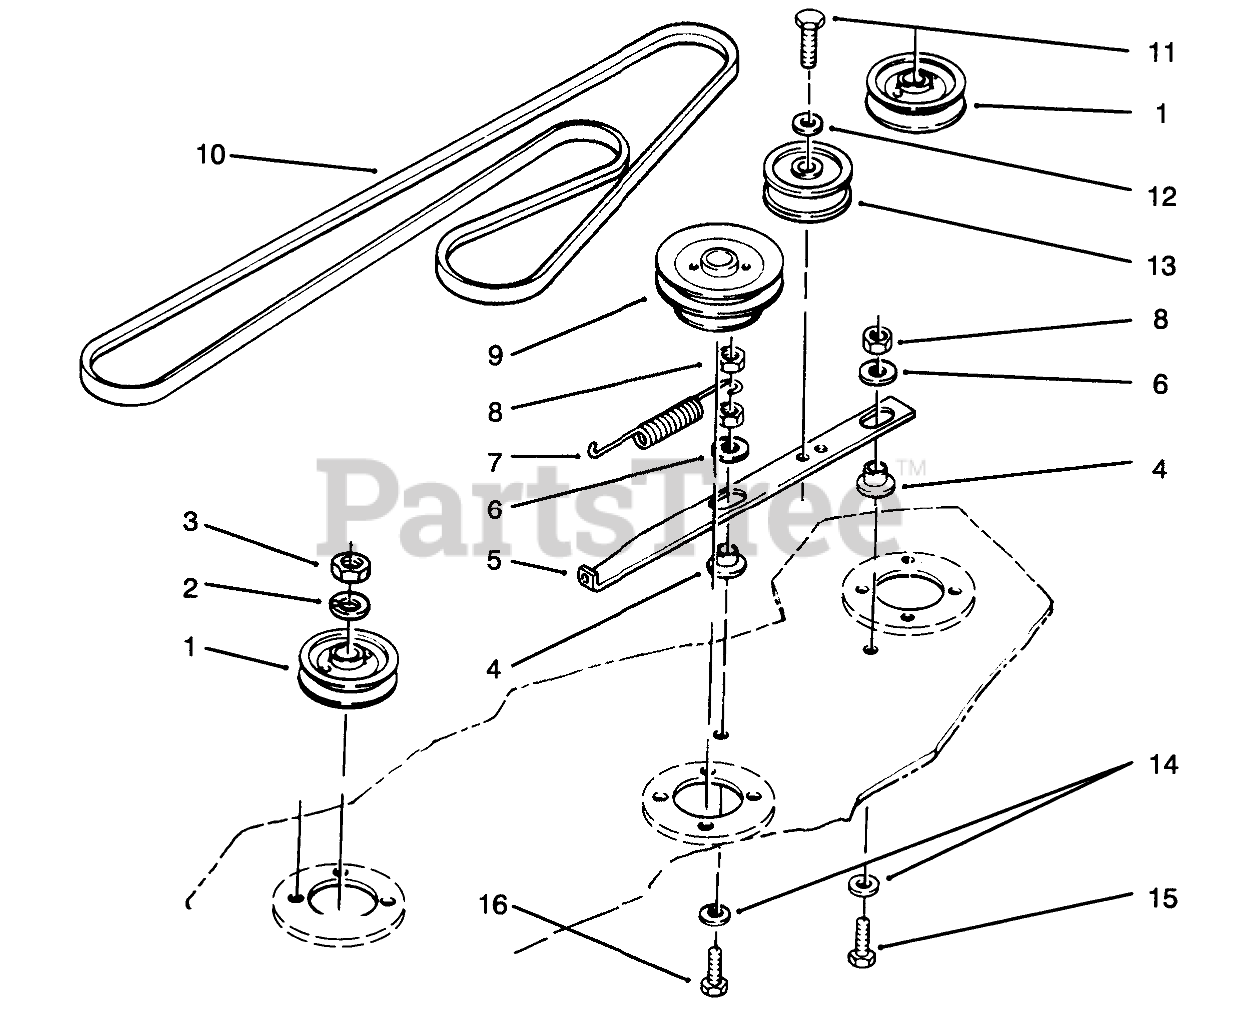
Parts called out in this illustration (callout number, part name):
1	PULLEY
2	WASHER-LOCK
3	NUT-JAM
4	SPACER-BUSHING
5	BAR-IDLER SUPPORT
6	WASHER
7	SPRING-EXTENSION
8	NUT-LOCK, NI
9	PULLEY
10	V-BELT
11	SCREW-HH
12	Washer-Lock
13	Idler Pulley
14	WASHER
15	SCREW-HH
16	SCREW-HH
